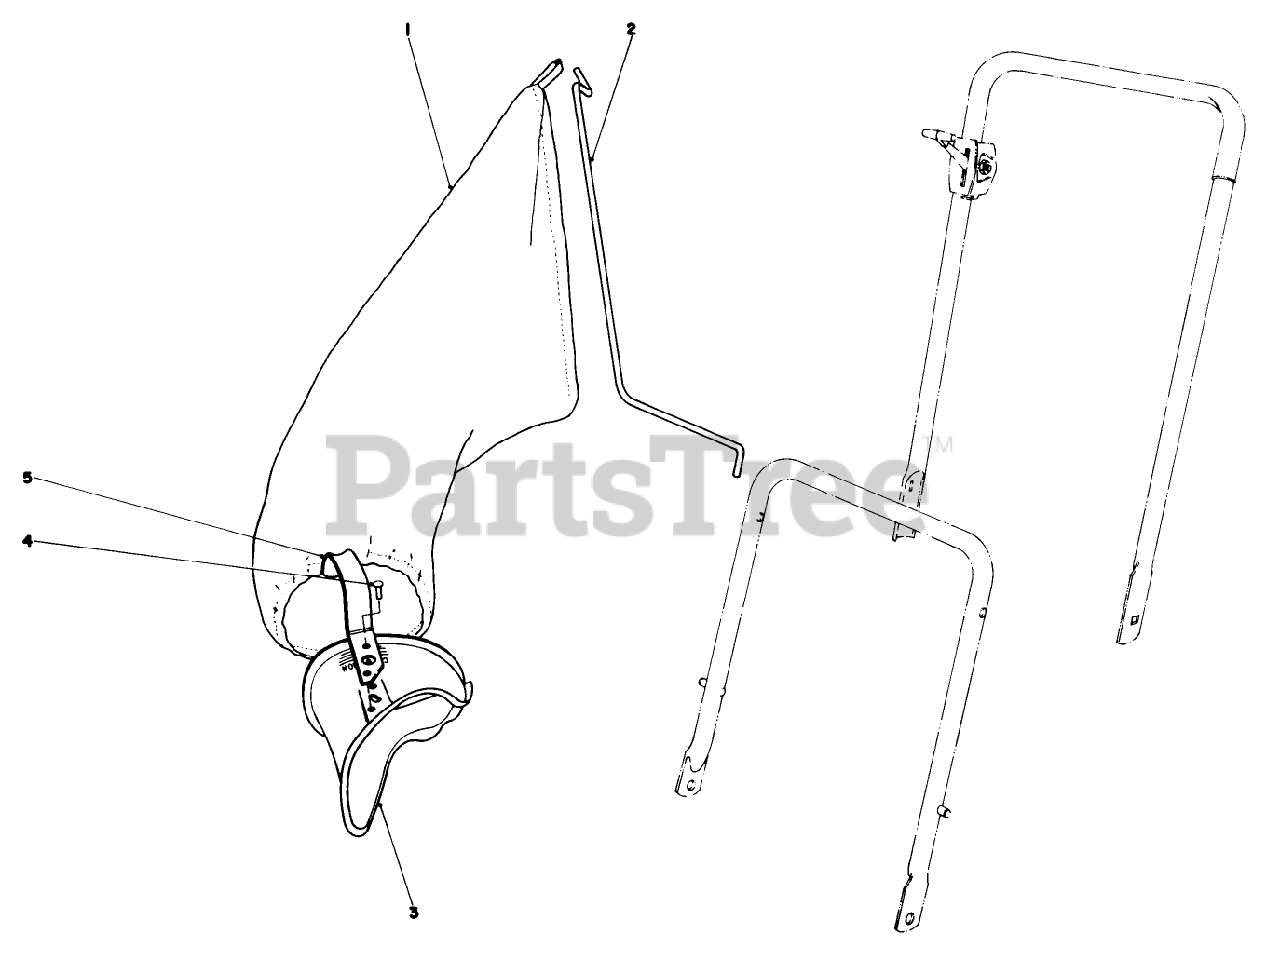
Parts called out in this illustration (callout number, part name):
2	BAG HANGER ROD
3	GRASS CHUTE ASM
4	RIVET 3/16 X 7/16
